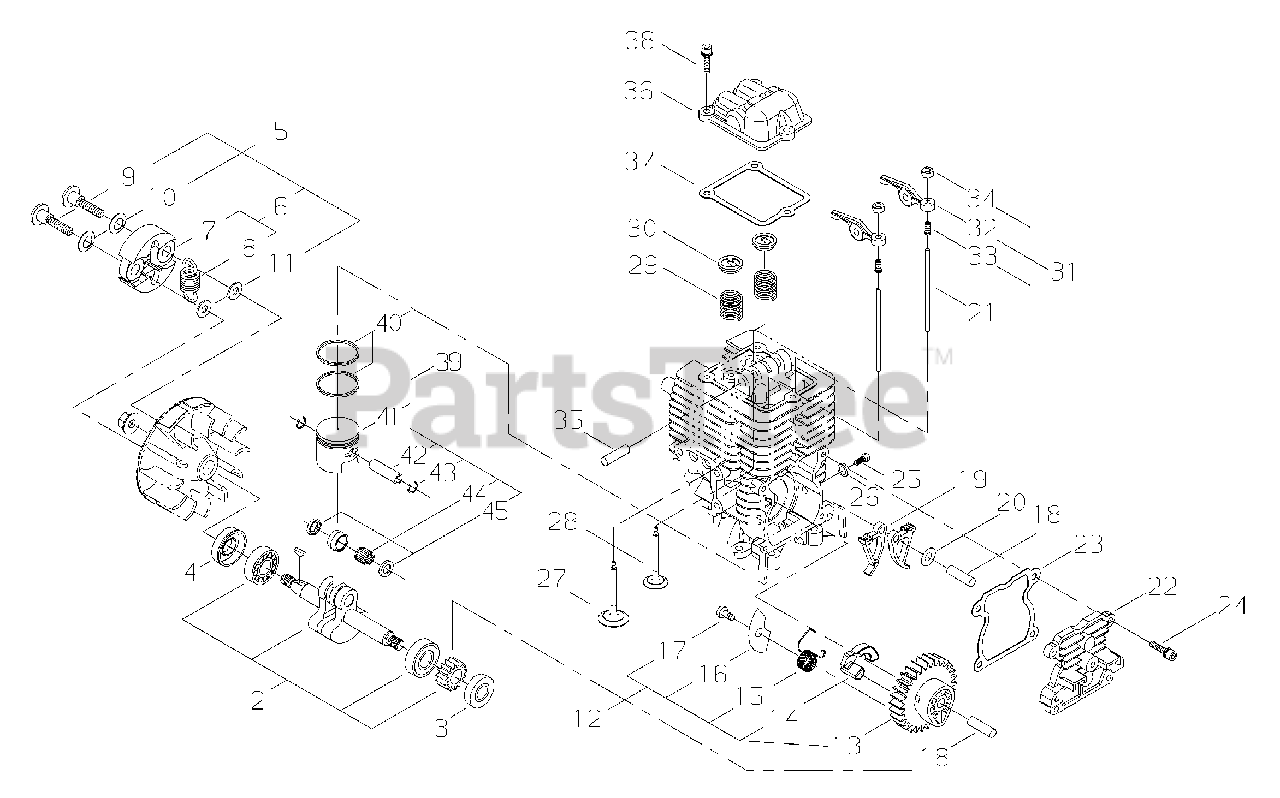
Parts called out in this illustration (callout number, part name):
2	CRANKSHAFT ASSY
3	SEAL, OIL - 12
4	SEAL, OIL
5	CLUTCH SHOE ASSY
6	CLUTCH SHOE ASSY
7	SHOE, CLUTCH
8	SPRING, CLUTCH
9	BOLT, CLUTCH
10	WASHER - SPRING
11	WASHER - 6
12	CAM GEAR ASSY
13	GEAR, CAM
14	WEIGHT
15	SPRING
16	PLATE
17	SCREW - 4X6 -- TAPPING
18	PIN - LOCATING
19	FOLLOWER, CAM
20	WASHER - 5
21	PUSHROD
22	COVER, CAM GEAR
23	GASKET
24	SCREW - 4X14
25	SCREW - 5
26	WASHER
27	VALVE, INTAKE
28	VALVE, EXHAUST
29	SPRING, VALVE
30	VALVE RETAINER ASSY
31	ROCKER ARM ASSY
32	ARM, ROCKER
33	SCREW, ADJUST
34	LOCKNUT, ADJUSTER
35	SHAFT, ROCKER ARM - 5X37.8
36	COVER, ROCKER ARM
37	GASKET
38	SCREW - 4X14
39	PISTON KIT
40	RING, PISTON
41	PISTON
42	PIN, PISTON
43	RING, RETAINING
44	BEARING, NEEDLE
45	WASHER, THRUST - 10
